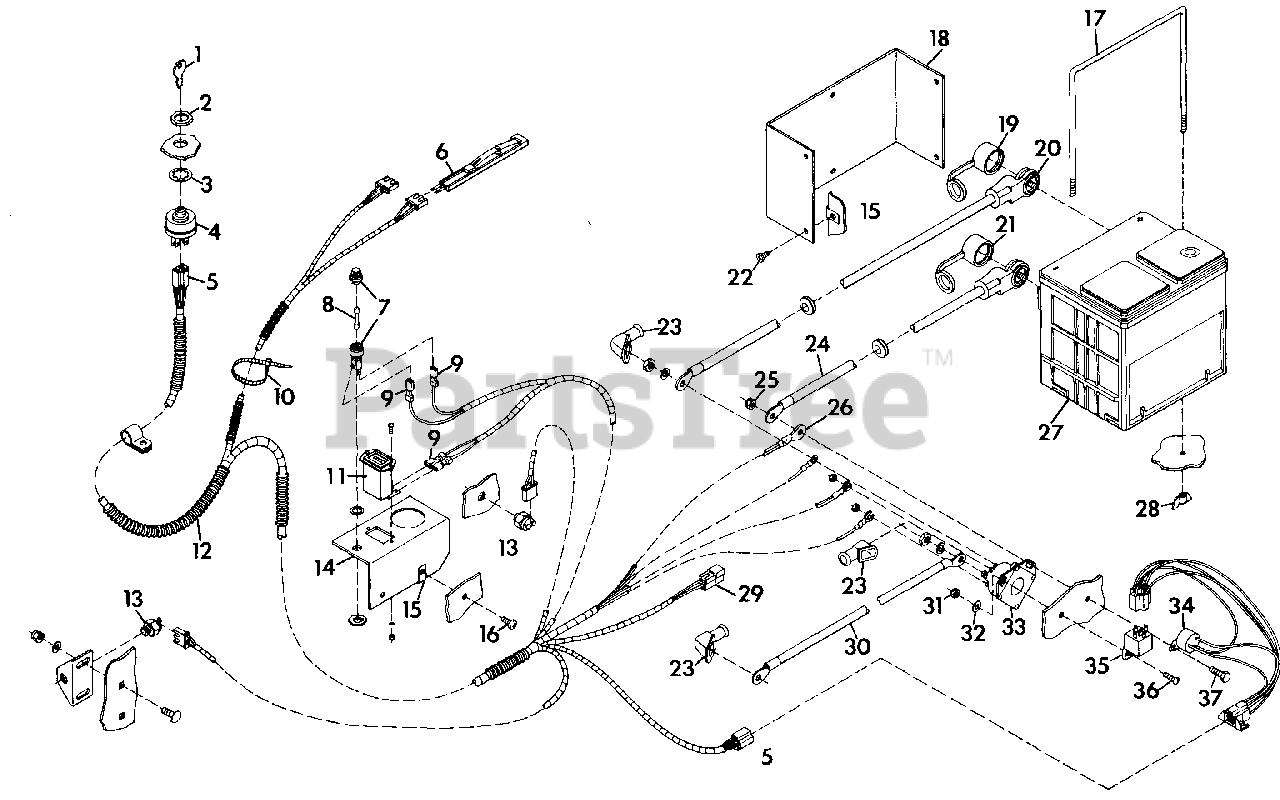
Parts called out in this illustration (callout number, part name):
1	KEY, IGNITION SWITCH
2	NUT, JAM 9/16-24
3	WASHER, LOCK
4	SWITCH, IGNITION
5	CONNECTOR
6	SWITCH, SEAT
7	FUSE, PANEL
8	FUSE, 30 AMP AGC-30
9	TERMINAL
10	TIE, CABLE
11	HOURMETER
12	HARNESS, WIRING
13	SWITCH, NEUTRAL START
14	PANEL, INSTRUMENT
15	NUT, RETAINER
16	SCREW, MACHINE 1/4-20 PAN HD
17	ROD, BATTERY
18	GUARD, BATTERY
19	COVER, BATTERY POSITIVE TERMINAL
20	CABLE, ELECTRICAL
21	COVER, BATTERY NEGATIVE TERMINAL
22	SCREW, MACHINE 1/4-20X.625
23	BOOT, BATTERY CABLE
24	GROMMET
25	NUT, LOCK 1/4-20
26	CABLE, ELECTRICAL
27	BATTERY, 12 VOLT
28	NUT, WING 1/4-20
29	CONNECTOR
30	CABLE, STARTER
31	NUT, LOCK 10-24
32	WASHER, FLAT .281X.625X.065
33	SWITCH, MAGNETIC
34	MODULE, TIME DELAY
35	RELAY
36	SCREW, MACH. 10-24X1.00 RD HD
37	BOLT, HEX 1/4-20X1.25
NS	WASHER, LOCK 1/4 EXT. TH TYA
